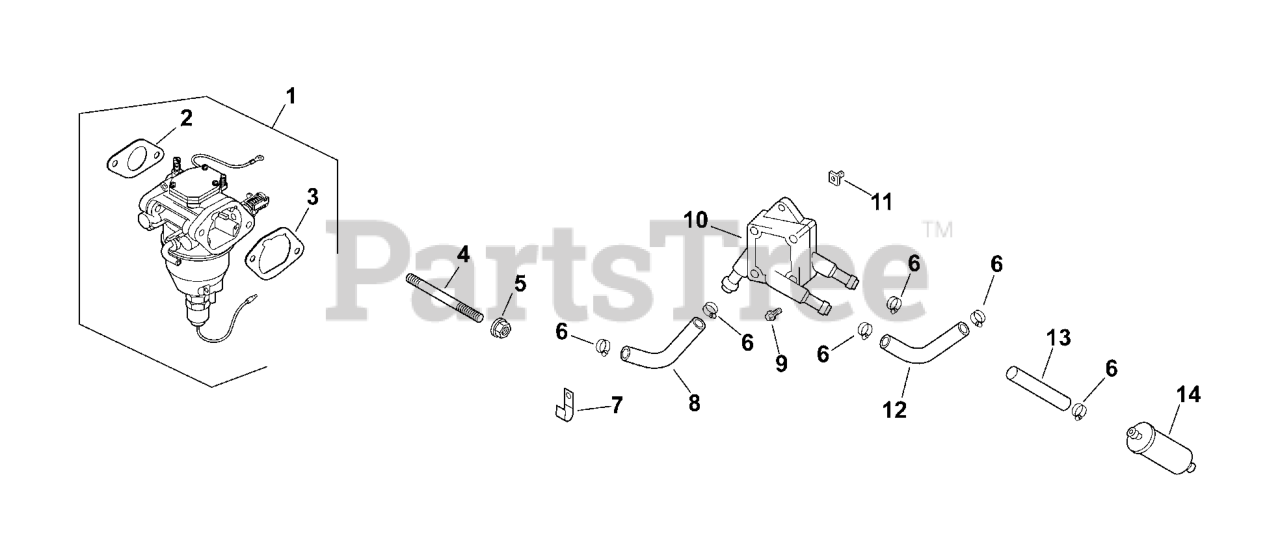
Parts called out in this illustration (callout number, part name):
1	KIT, CARBURETOR W/GASKET-NIKF
2	GASKET, CARBURETOR
3	GASKET, AIR CLEANER BASE
4	STUD,M6X1.0X128
5	NUT, FLG M6X1.0
6	CLAMP, HOSE (KM)-USE 25 237 31-S
7	CLIP, CABLE
8	LINE, FLEXIBLE FUEL 12.3"-USE 25 111 81-
9	SCREW, TAP M6X1.7X18
10	PUMP, FUEL
11	NUT, PLASTIC (KM)-USE 25 100 37-S
12	LINE, FUEL 11"
13	LINE FLEXBLE FUEL (3.5" x.25") -USE 25 1
